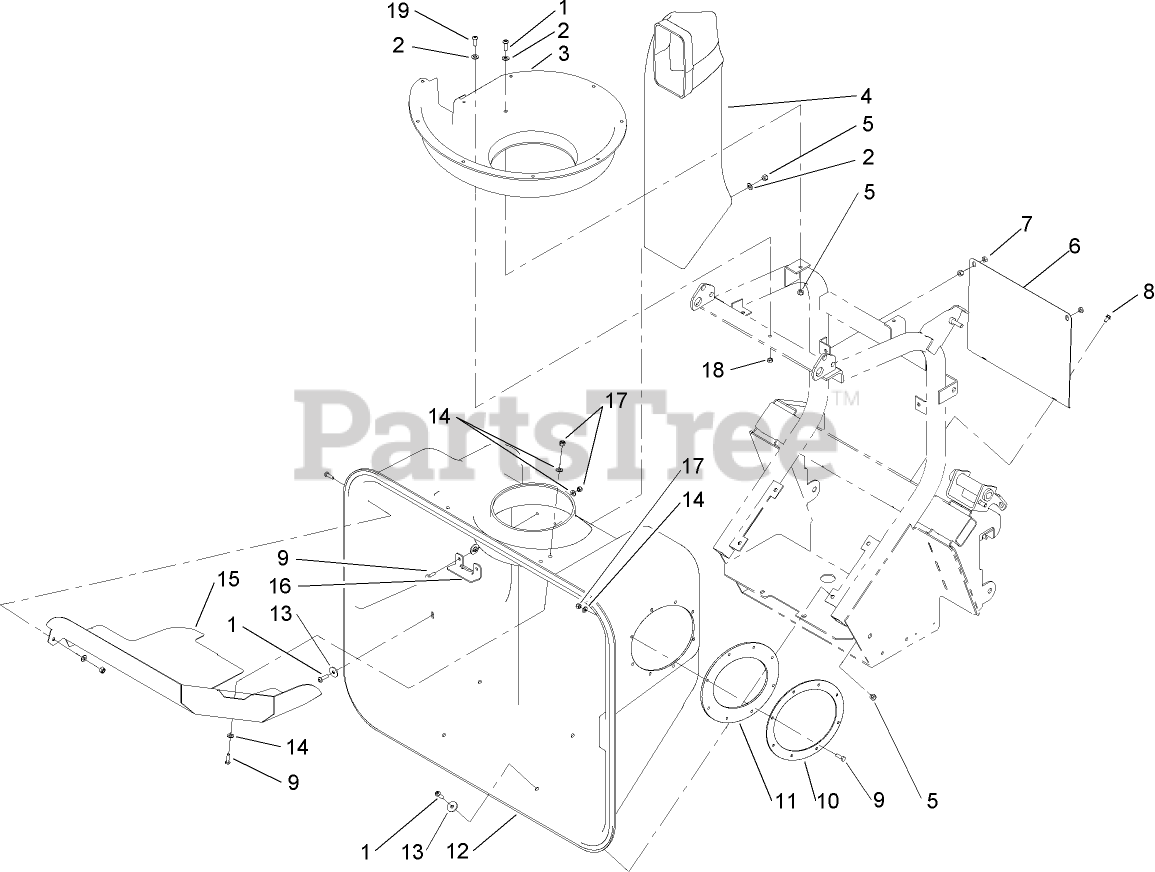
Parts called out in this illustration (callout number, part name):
1	SCREW-HSBH
2	WASHER-PLAIN
3	SCROLL-BOTTOM
4	TUBE-EXHAUST
5	NUT-LOCK, NI
6	SHIELD-HEAT
7	NUT-JAM
8	SCREW-HWH
9	SCREW-HH
10	PLATE-SEAL
11	SEAL-RUBBER
12	HOPPER-FRONT
13	WASHER-FLAT
14	WASHER-FLAT
15	SCREEN ASM
16	BRACKET-SCREEN, LOWER
17	NUT-LOCK, NI
18	NUT-LOCK, NI
19	SCREW-HSBH
